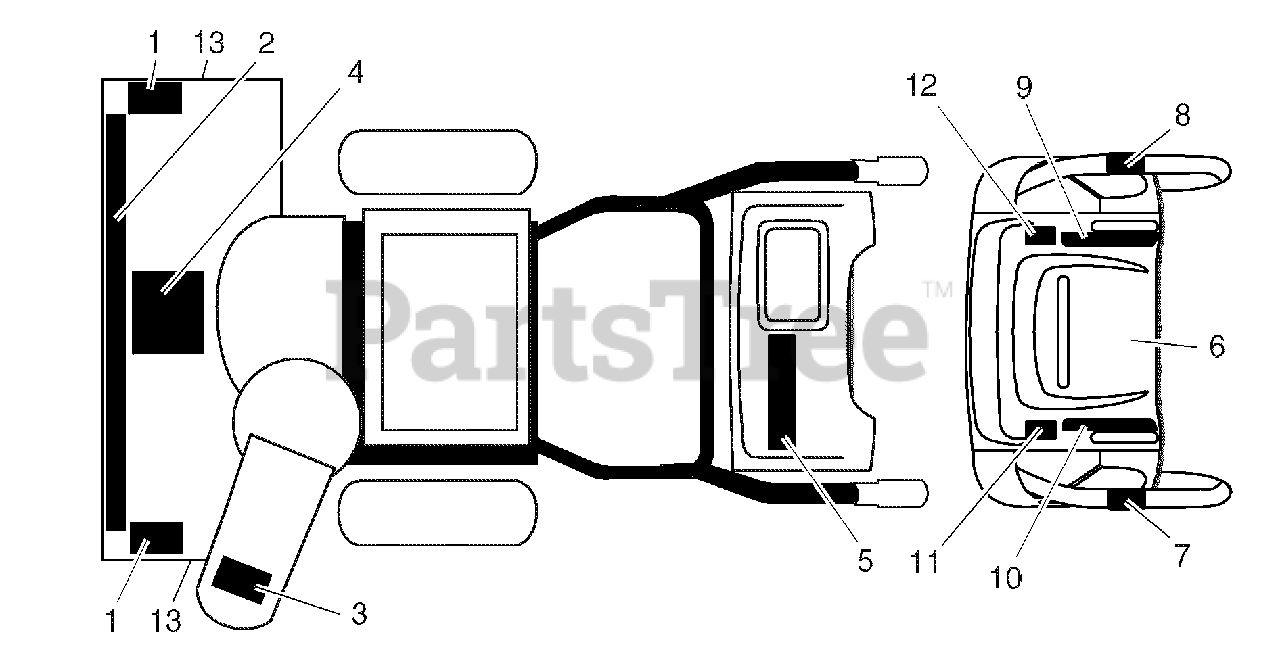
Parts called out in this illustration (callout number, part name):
1	Decal, Danger
2	Decal, Husqvarna
3	Decal, Danger, Deflector
4	Decal, Danger
5	Decal, Husqvarna, 10527SBE
6	Decal, Instruction
7	Decal, Traction Lever
8	Decal, Auger Lever
9	Decal, Speed Control
10	Decal, Remote Deflector
11	Decal, LH Trigger
12	Decal, RH Trigger
13	Decal, Husqvarna, Crown
